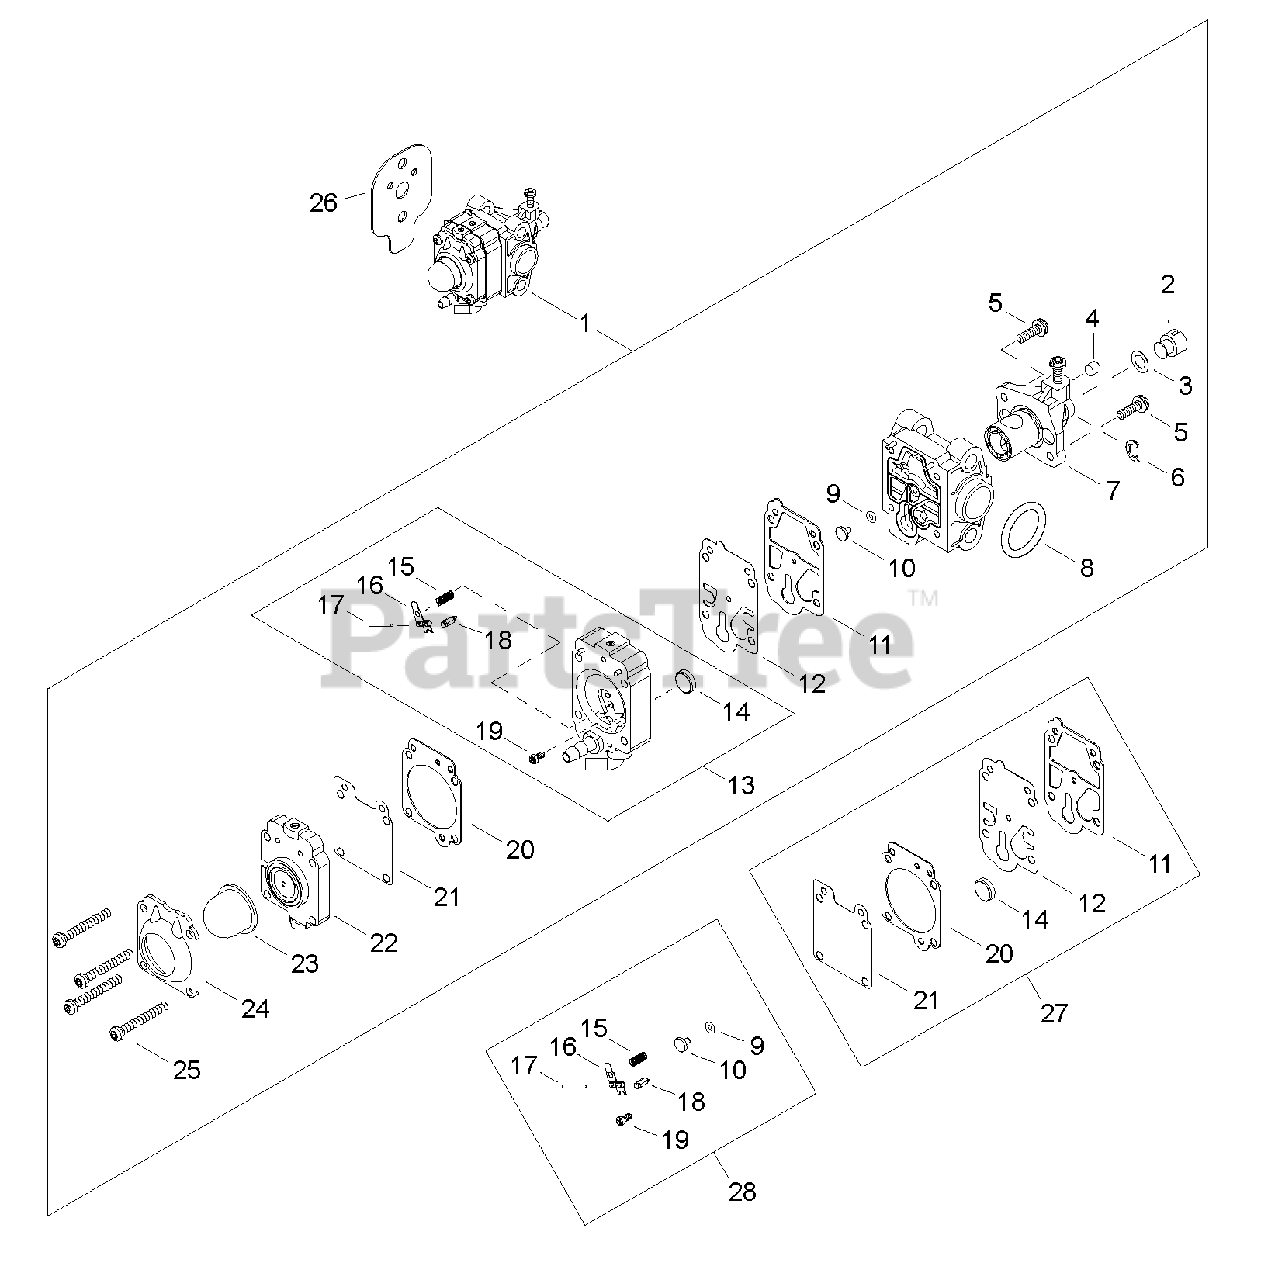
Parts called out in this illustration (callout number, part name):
1	CARBURETOR
2	SWIVEL
3	WASHER
4	CAP, LIMITER
5	SCREW
6	RING, RETAINING
7	THROTTLE VALVE ASSY
8	O-RING - 15
9	O-RING
10	JET, MAIN
11	GASKET, PUMP
12	DIAPHRAGM, PUMP
13	PUMP BODY ASSY
14	STRAINER
15	SPRING, METERING LEVER
16	LEVER, METERING
17	PIN, METERING LEVER
18	VALVE, INLET NEEDLE
19	SCREW, METERING LEVER PIN
20	GASKET, METERING
21	DIAPHRAGM, METERING
22	BASE, PURGE
23	BULB, PURGE
24	RETAINER, PURGE BULB
25	SCREW, PUMP COVER
26	GASKET, INTAKE
27	DIAPHRAGM/GASKET KIT
28	INLET NEEDLE VALVE KIT
